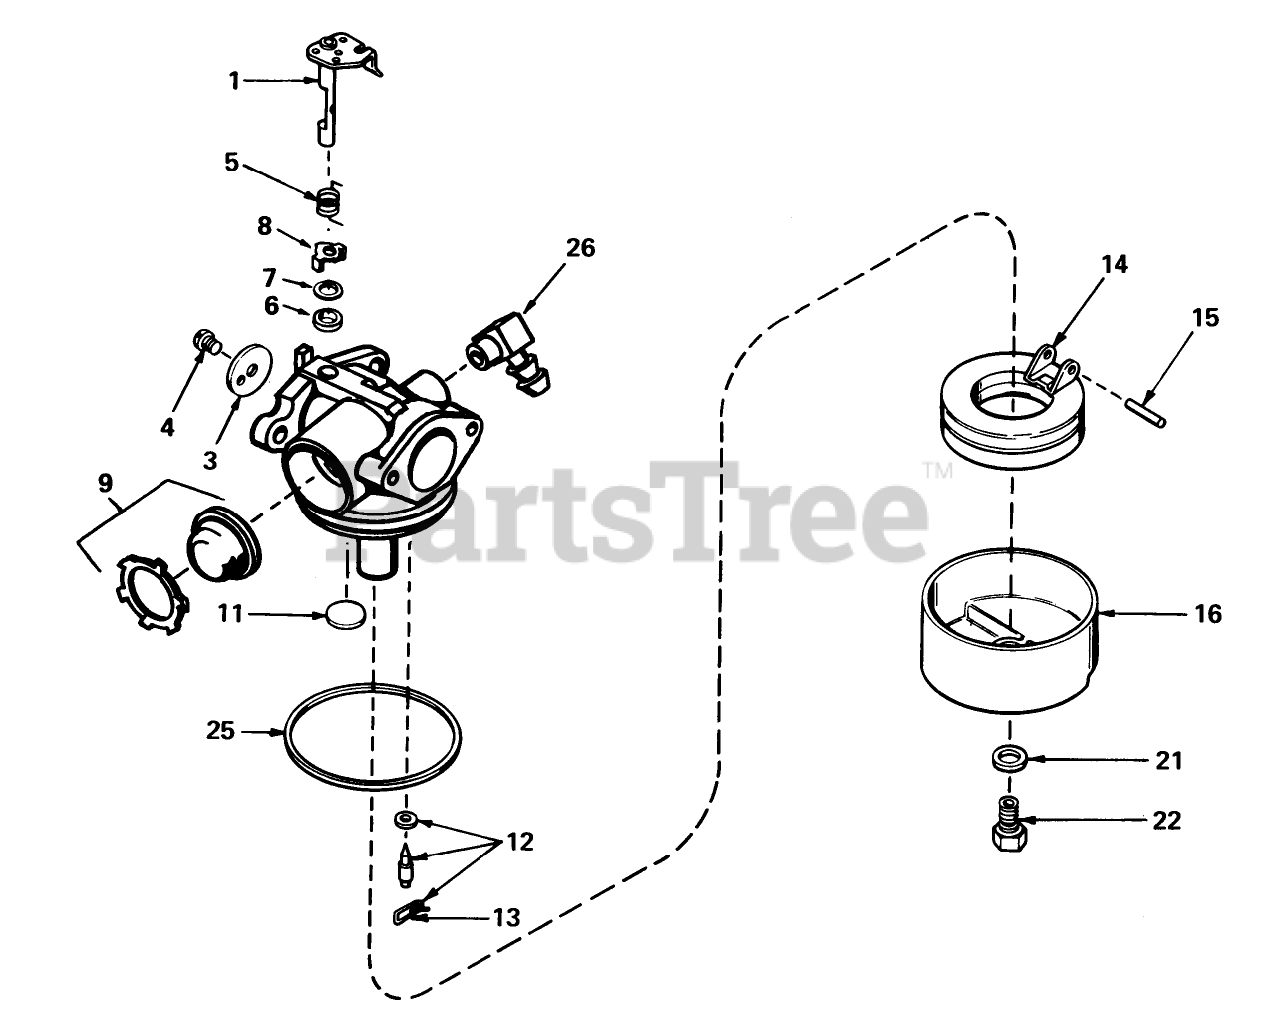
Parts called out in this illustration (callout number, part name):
1	Throttle Shaft and Lever ASM
3	Throttle-Shutter
4	Screw-Shutter
5	Spring, Return
6	Seal-Dust
7	Washer-Seal, Dust
8	Retainer, Seal
9	Primer Assy.
11	Plug-Welch, Atmospheric Vent
12	Inlet Needle, Seat Clip Assy. (Incl. No. 13)
13	Clip-Spring
14	Float
15	Shaft-Float
16	Bowl Float
21	Gasket-Bowl
22	Nut-Float Bowl
25	O Ring-Bowl, Float
26	Fitting-Fuel
